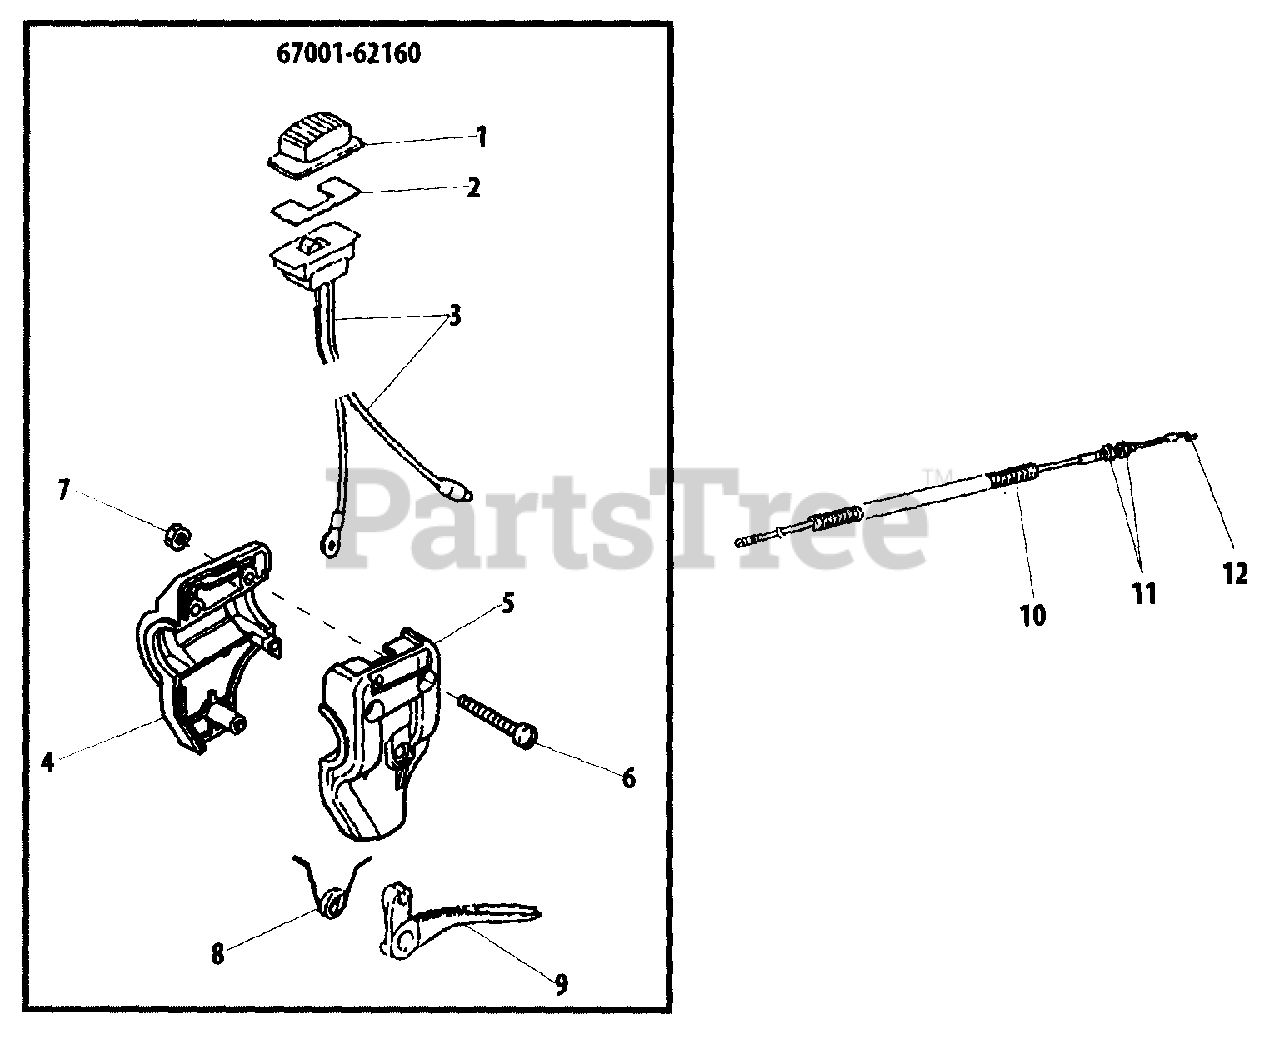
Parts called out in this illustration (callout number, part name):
1	KNOB
2	PLATE, SWITCH
3	SWITCH, IGNITION
4	BRACKET - RIGHT
5	BRACKET L
6	SCREW - 5X30
7	NUT - 5
8	SPRING, TRIGGER
9	TRIGGER, THROTTLE
10	TUBE
11	NUT - 6
12	CABLE, THROTTLE
67001-62160	THROTTLE LEVER ASSY
